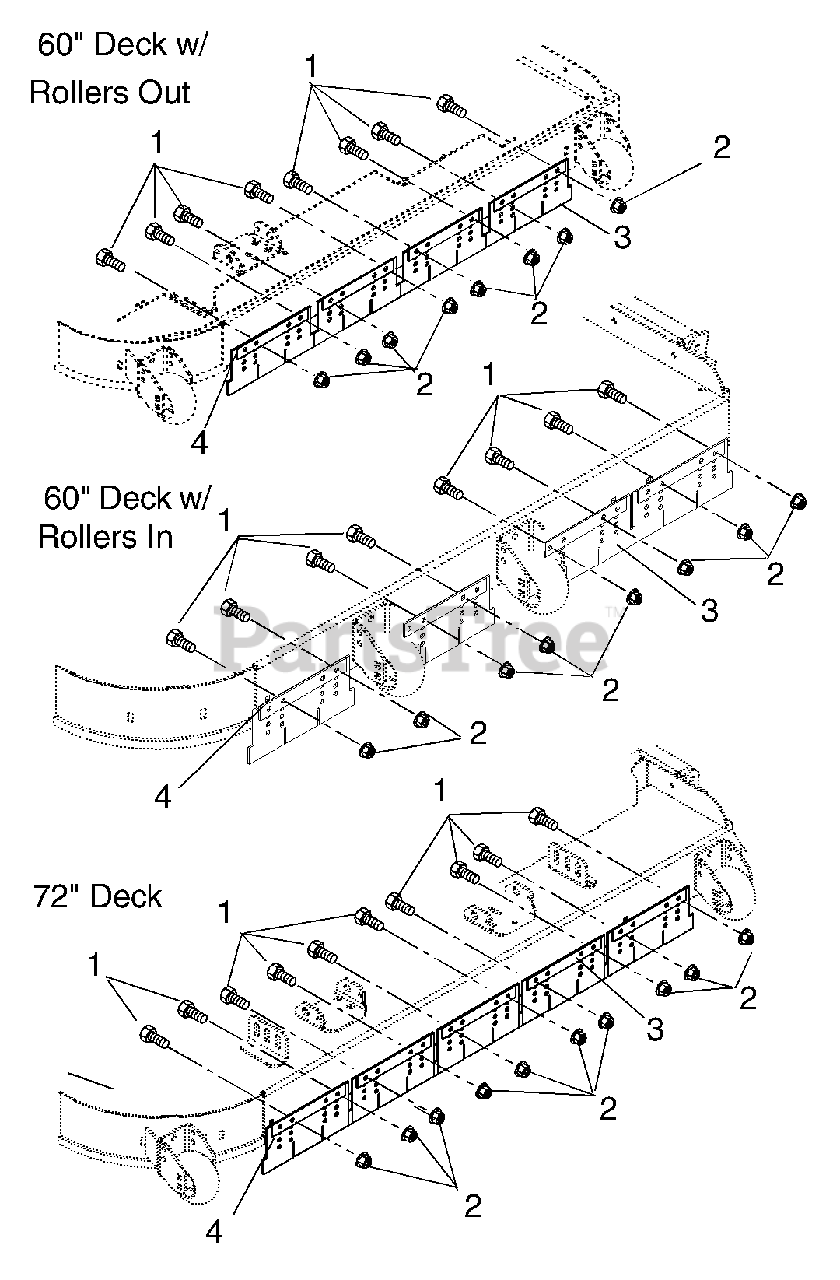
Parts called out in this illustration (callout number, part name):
1	Hex Bolt, 3/8"-16 x 1" Grade 5
2	Top-Locking Flange Nut,3/8"-16
3	Rubber Striper Skirt
4	Striper Bar
